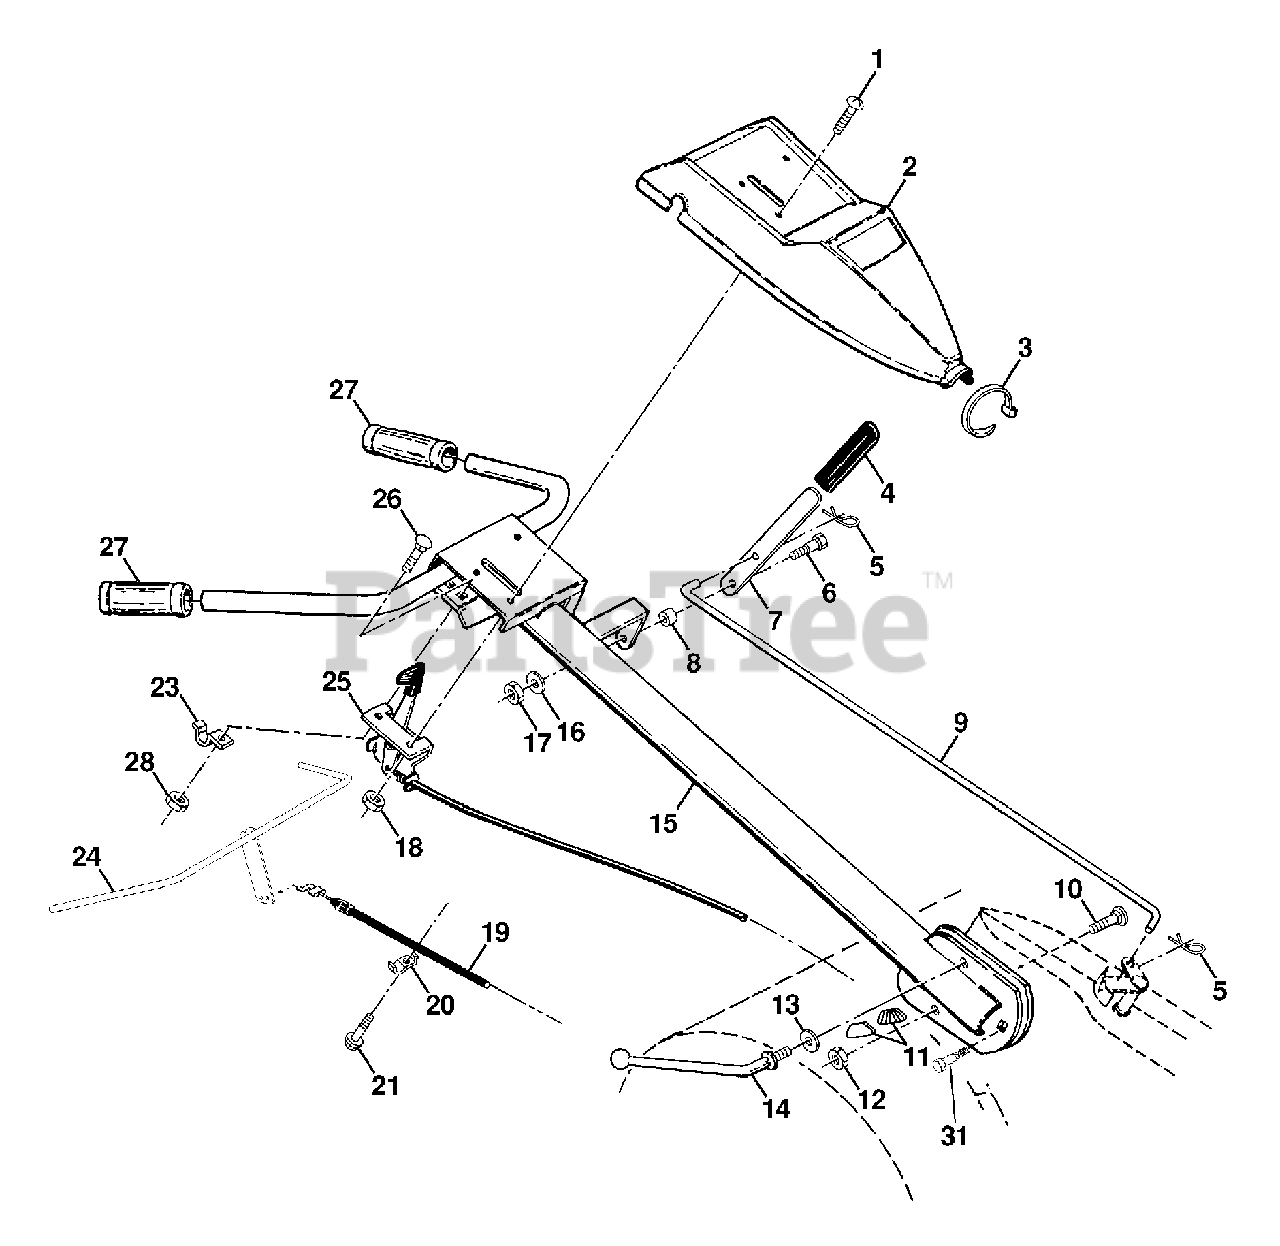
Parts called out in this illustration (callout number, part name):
1	Screw, Phd. #10-24 UNC
2	Panel, Control
3	Tie, Cable
4	Grip, Handle
5	Clip, Hairpin
6	Bolt, Shoulder
7	Handle, Shift
8	Grommet, Rubber
9	Rod, Shift
10	Bolt, Carriage 3/8-16 x 1 Gr. 5
11	Lock, Handle
12	Nut, Centerlock 3/8-16
13	Washer 13/32 x 1 x 11 Ga.
14	Lever, Lock, Handle
15	Handle
16	Washer, Lock 1/4
17	Nut, Hex 1/4-20
18	Nut, Keps #10-24 UNC
19	Cable, Clutch
21	Screw, Hex Washer Hd. Slotted #10-24 x 1/2
22	Grip, Bar, Control
23	Clamp, Bar, Control
24	Bar Assembly, Control
25	Control, Throttle
26	Bolt, Carriage 1/4-20 UNC x 1/2
27	Grip, Handle
28	Nut, Keps Hex 1/4-20
31	Bolt Pivot
